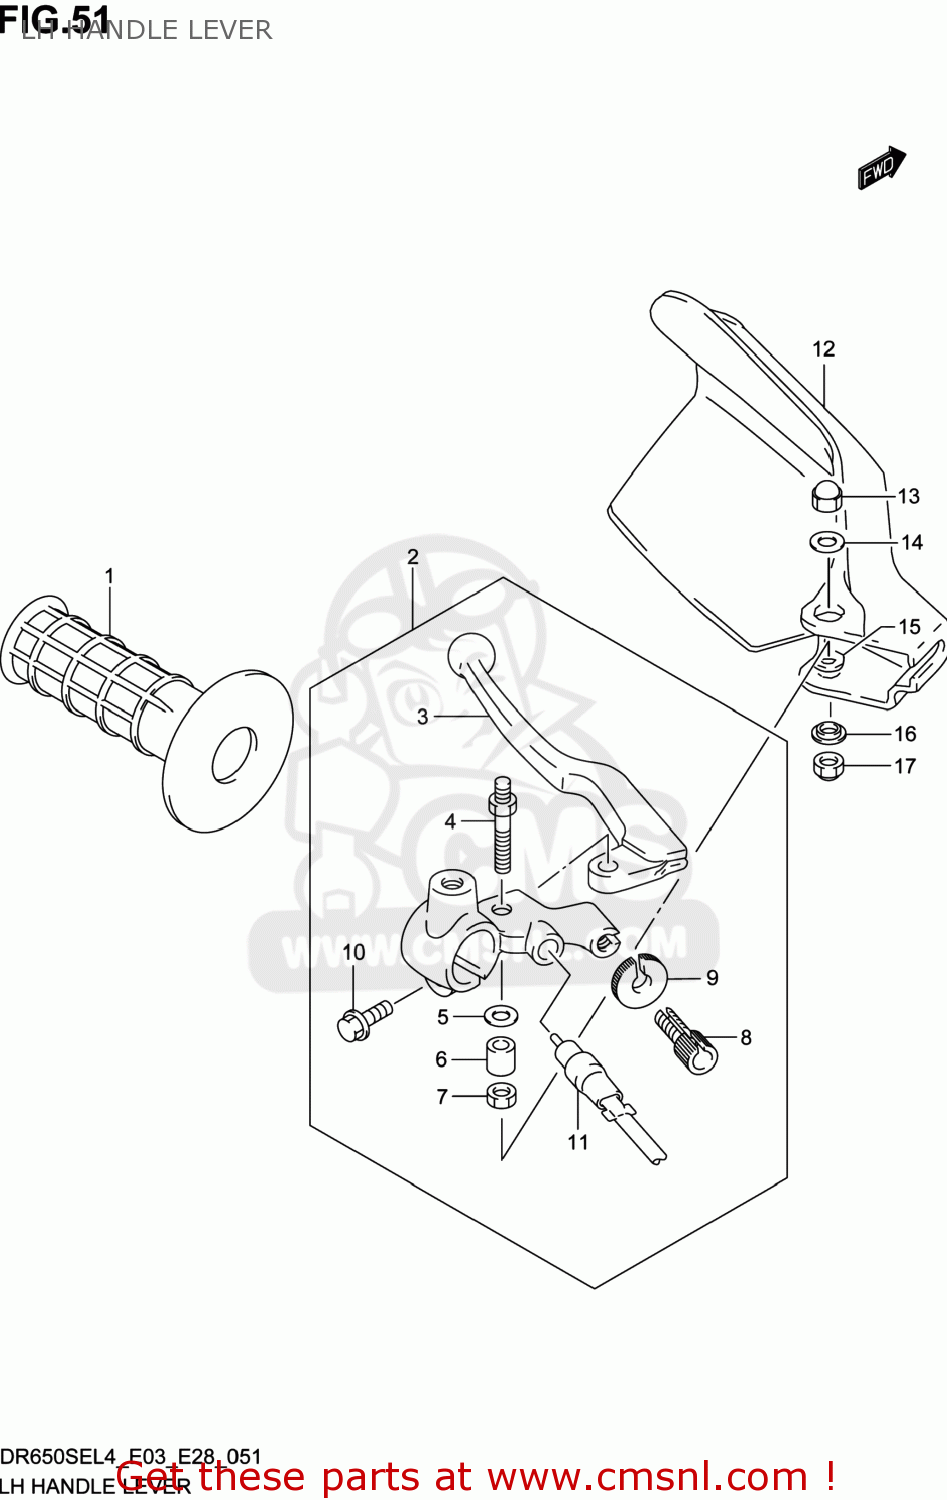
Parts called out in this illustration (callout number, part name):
1	GRIP,L
2	LEVER ASSY,CLUTCH
3	LEVER,CLUTCH
4	BOLT,PIVOT
5	WASHER
6	SPACER
7	NUT
8	ADJUSTER,WIRE
9	NUT,LOCK
10	BOLT
11	SWITCH ASSY,CLUTCH
12	COVER,KNUCKLE,L
13	NUT
14	WASHER(6.5X20X1.6)
15	WASHER(6.5X16X1.2)
16	WASHER
17	NUT
